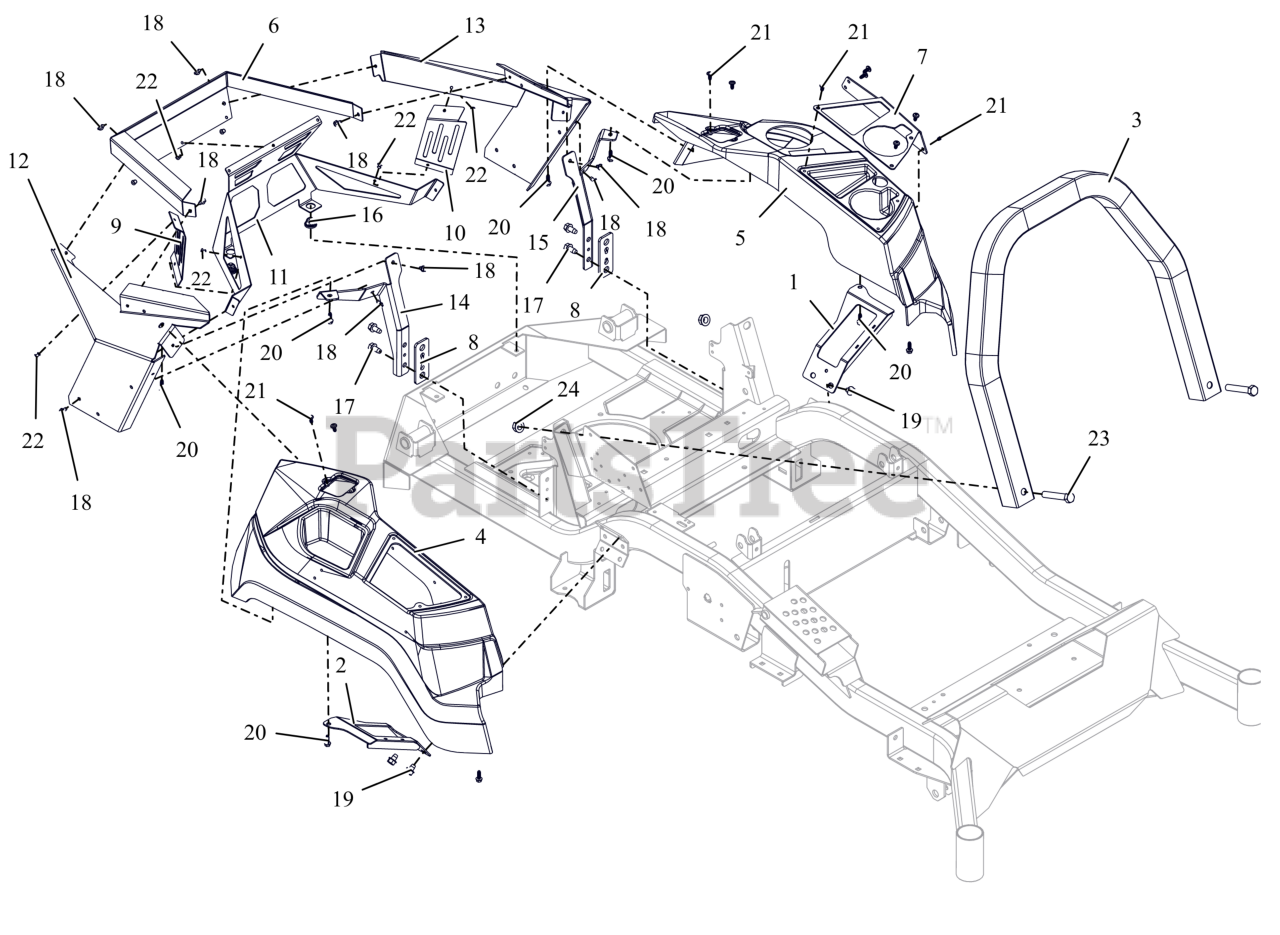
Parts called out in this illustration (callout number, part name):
1	WLDMT, LH FENDER MOUNT
2	WLDMT, RH FENDER MOUNT
3	GUARD, ENGINE -TOP (ORANGE)
4	FENDER, RH APEX - 2017
5	FENDER, LH APEX
6	GUARD,ENGINE WRAP
7	PLATE, APEX CUP HOLDER COVER
8	PLATE, CONTROL PANEL SPACER
9	SHIELD,RH ENGINE GUARD VALVE
10	SHIELD,LH ENGINE GUARD VALVE
11	GUARD, ENGINE
12	PANEL, RH REAR FENDER MOUNT
13	PANEL, LH REAR FENDER MOUNT
14	BRKT, RH FENDER MTG (ORANGE)
15	BRKT, LH FENDER MOUNT (ORANGE)
16	GROMMET, 10MM BOLLHOFF
17	SCR,TAP .375-16X.75 HWH TR ZCC
18	SCR,TAP .25-20X.375 HWH TR ZCC
19	SCR,TAP .375-16X.50 HWH TR ZCC
20	SCR, PLASTITE .25-10X.75 ZCC
21	SCR-PAN .25-15X.50 6L H/LZB500
22	RIVET, .1875 AL/AL .126-.250
23	BLT, HEX .50-13X3.00 G5 ZCC
24	NUT-LK-CTR-FLG .500-13 GG ZCC
